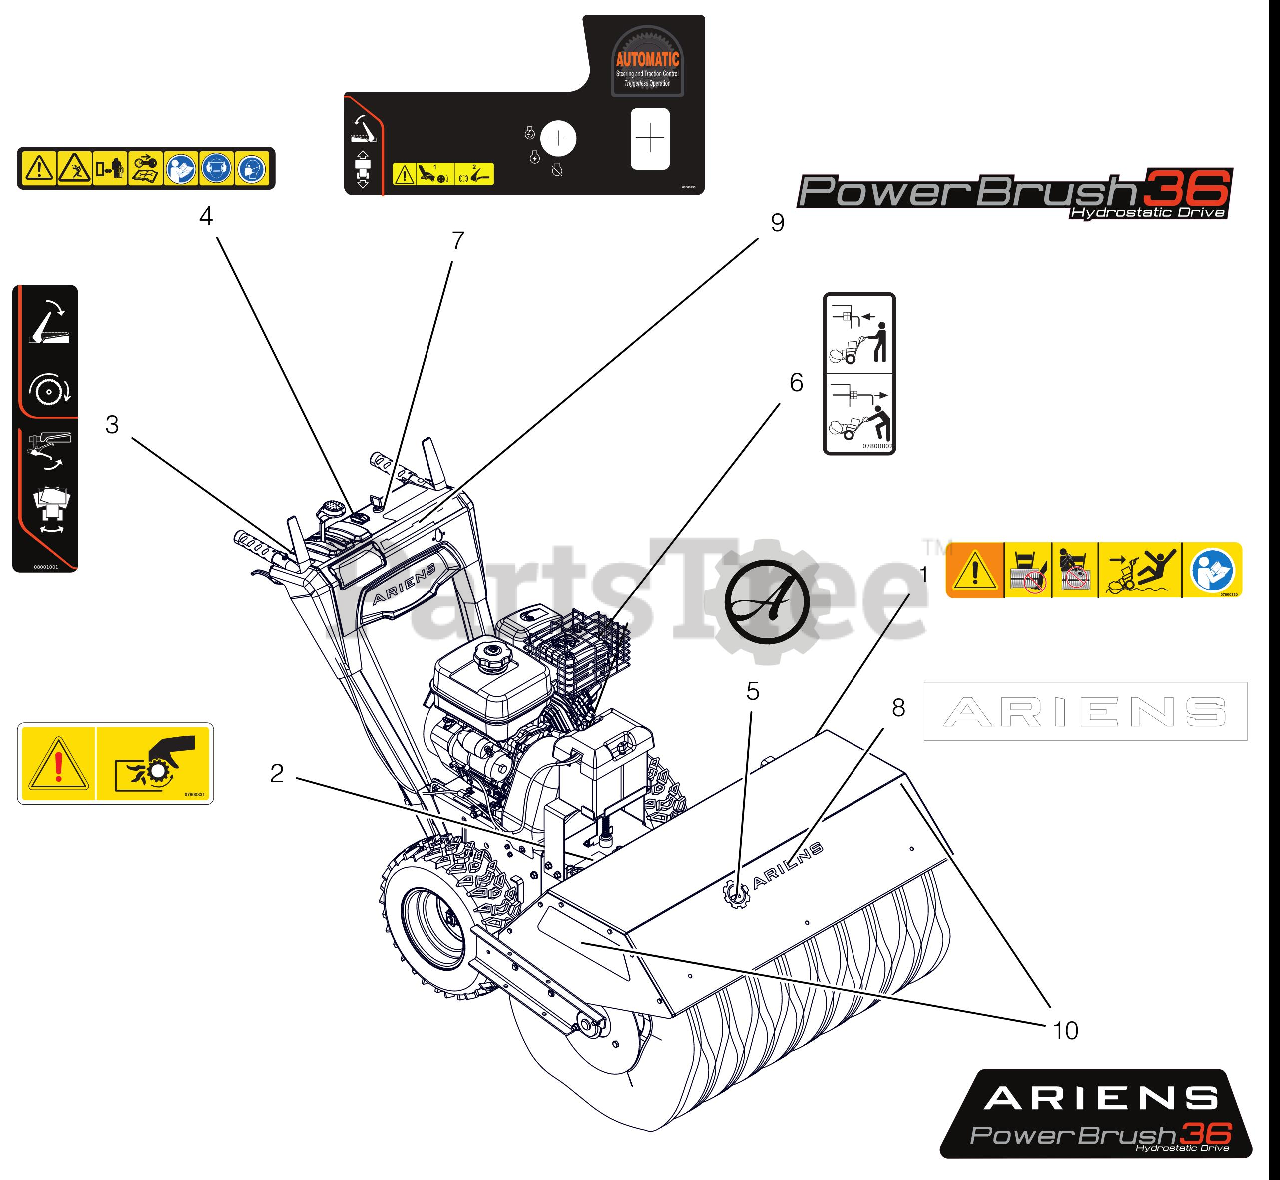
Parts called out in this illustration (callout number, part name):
1	DECAL, DANGER -POWER BRUSH-CE
2	DECAL, PTO WARNING
3	DECAL,CONTROL,BRUSH,RH
4	DECAL, SAFETY, DASH, BRUSH
5	DECAL, ARIENS-GEAR BADGE
6	DECAL, HYDRO BRUSH BYPASS
7	DECAL,CNTRL,LRG BRUSH,LH,HYDRO
8	DECAL - ARIENS 9.625"
9	DECAL, DASH - PB 36 HYDRO
10	DECAL - ARIENS PB 36 HYDRO
